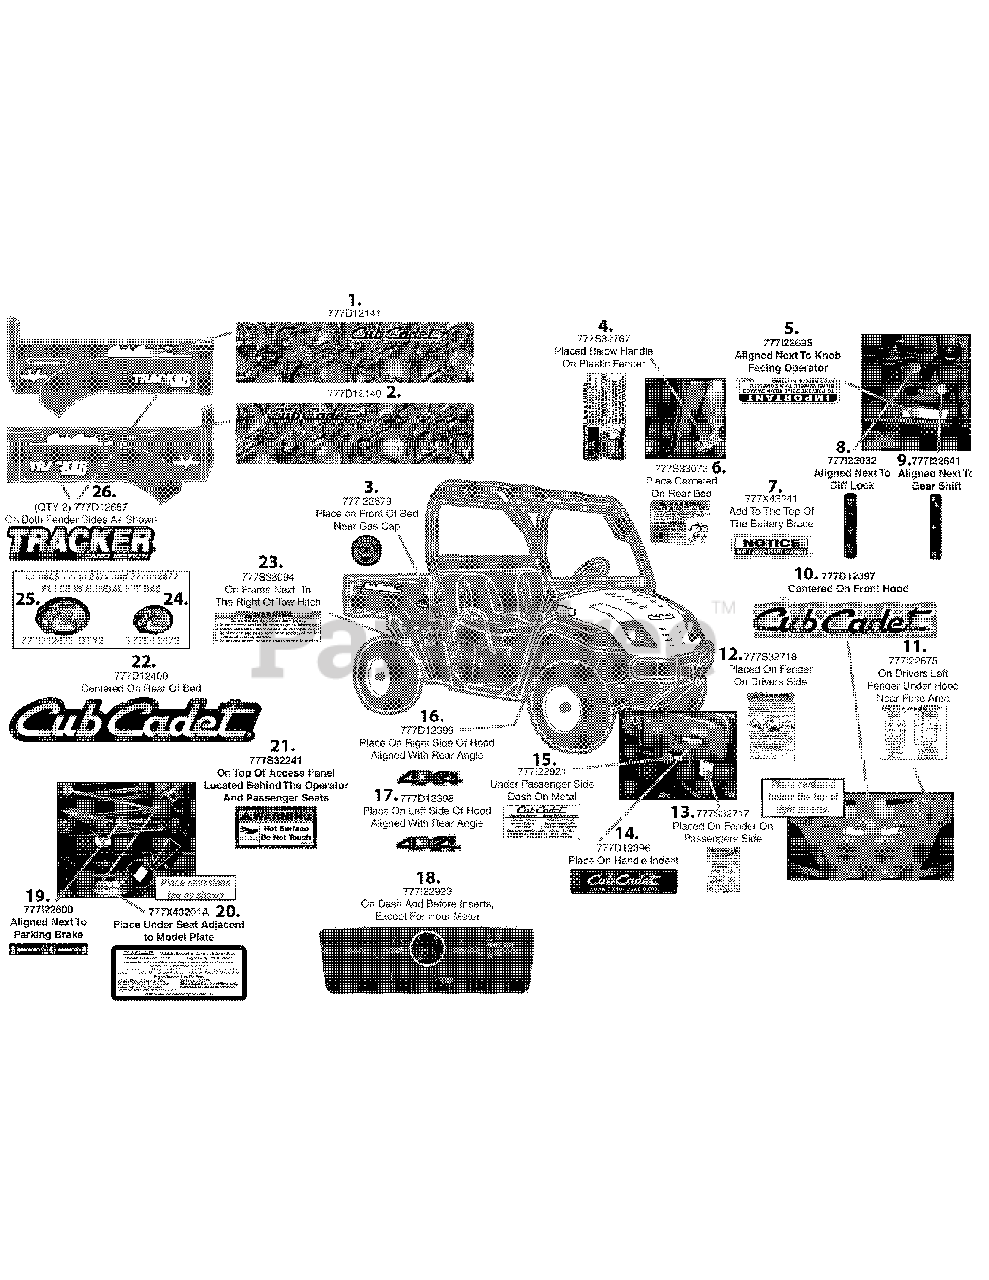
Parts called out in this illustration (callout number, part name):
1	LABEL-CUB UV:TRACKER LEFT
2	LABEL-CUB UV:TRACKER RIGHT
3	LABEL-CHECK ENG OIL
4	LABEL-4X4 CARGO BOX HANDLE
5	LABEL:4X4 SHIFT
6	LABEL:UV:4X4 CARGO BOX EFI
7	LABEL-DON'T JUMP BATTERY
8	LABEL-DIFF LOCK CO
9	LABEL-GEAR SHIFT
10	LABEL-UV:HOOD CUB TREESTAND
11	LABEL:UV:4X4 CAT FUSE
12	LABEL-ROLL & FALL LH FENDER
13	LABEL-RIDER FALL RH FENDER
14	LABEL-UV:DASH LOGO CAMO NEW
15	LABEL-UV:EFI WEIGHT
16	LABEL-CUB UV:4X4 HOOD RT SD TREE
17	LABEL-CUB UV:4X4 HOOD LT SD TREE
18	LABEL-UV:EFI DASH CK ENG
19	LABEL-PARK BRAKE
20	LABEL-UV:EFI EMISSIONS
21	LABEL-HOT SURFACE
22	LABEL-CUB UV:LOGO REAR BED TREE
23	LABEL-SAFTEY:TOWING EFI 1400 LB
24	LABEL-UTILITY:BASSPRO SMALL
25	LABEL-UTILITY:BASSPRO LARGE
26	LABEL-UV:TRACKERCAMO FENDER
